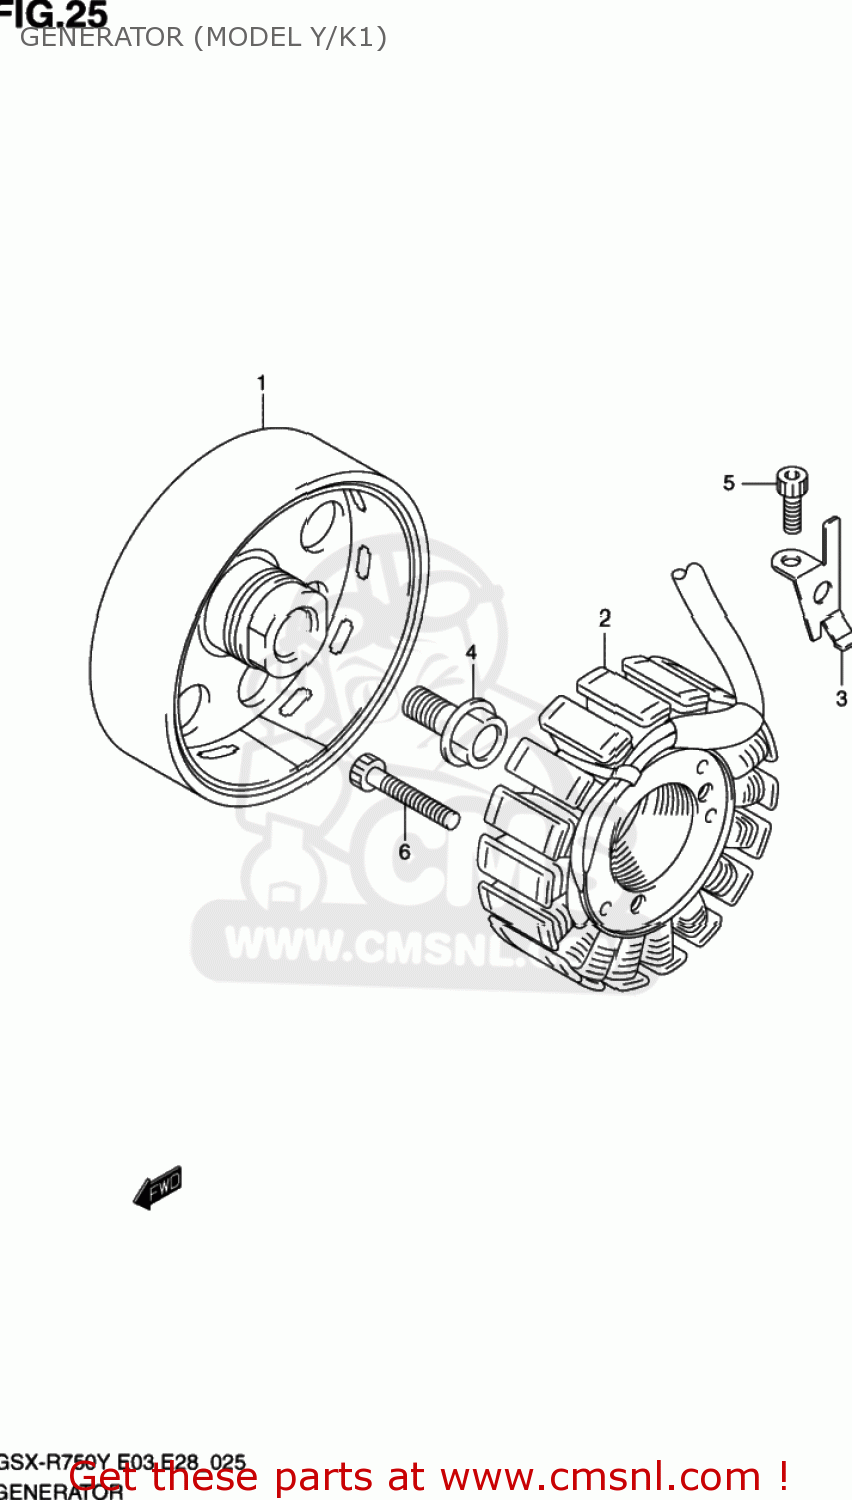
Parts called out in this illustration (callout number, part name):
1	ROTOR ASSY
2	STARTER ASSY
3	CLAMP,MAGNETO LEAD
4	BOLT(12X23)
5	BOLT,STRANGER
6	BOLT
